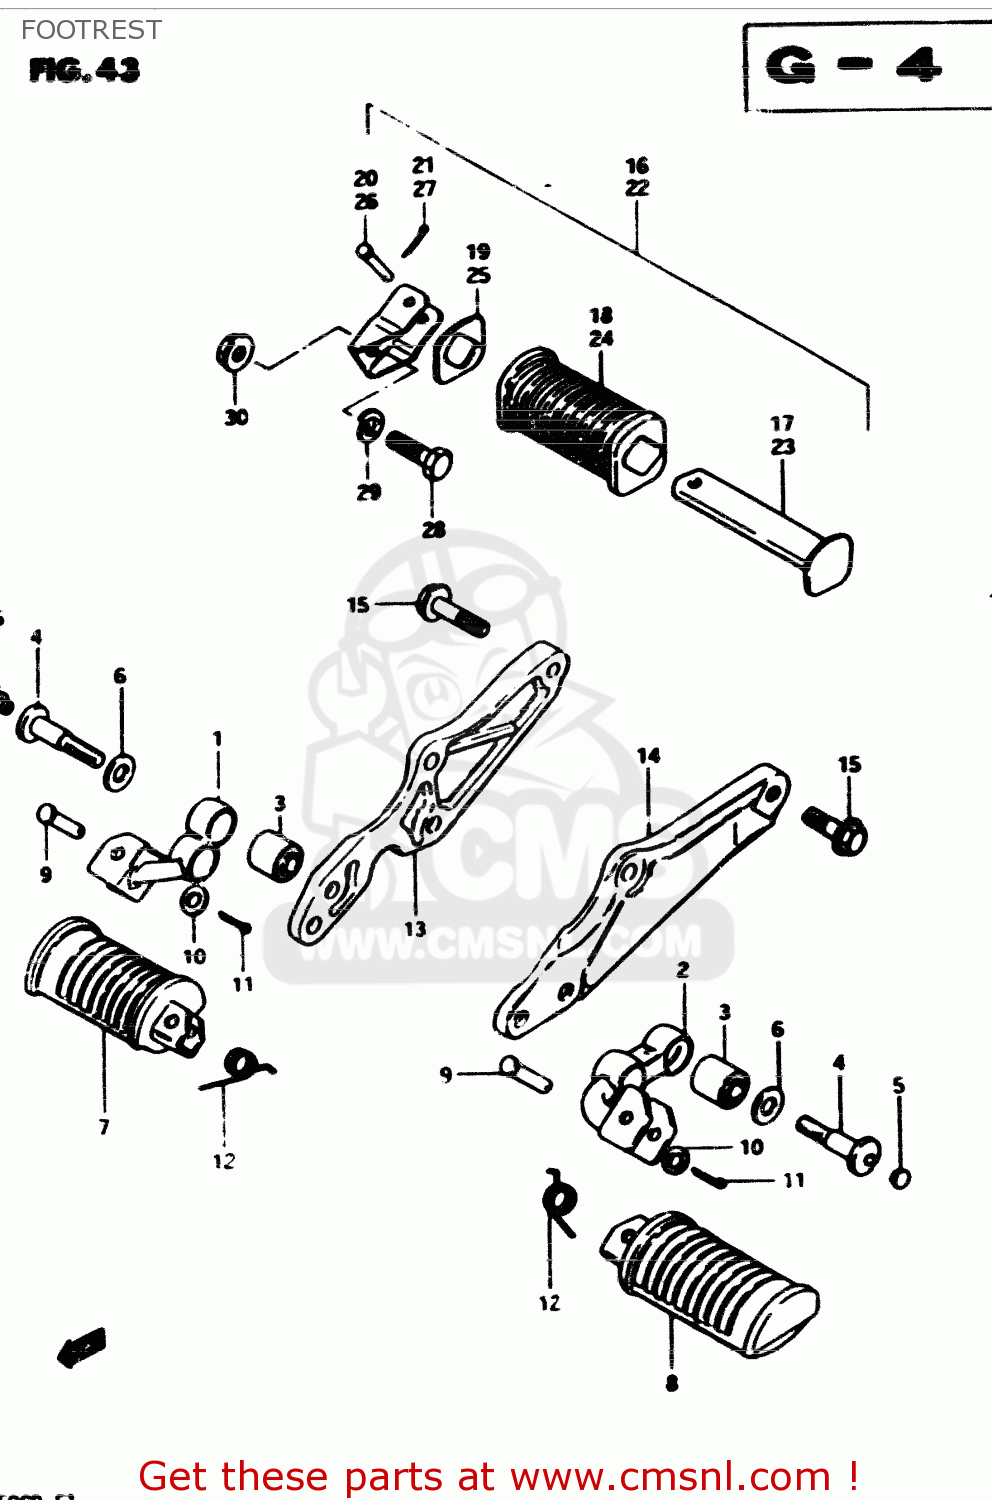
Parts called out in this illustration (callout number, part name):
1	BAR,FRONT FOOTREST,RIGHT
2	BAR,FRONT FOOTREST,LEFT
3	BUSH
4	BOLT(10X50)
5	CAP
6	WASHER(10.5X20X3.2)
7	RUBBER,PILLION FOOTREST,R
8	RUBBER,PILLION FOOTREST,L
9	PIN
10	WASHER
11	PIN 20X20
12	SPRING
13	BRACKET,MUFFLER,RIGHT
14	BRACKET,MUFFLER,LEFT
15	BOLT
16	FOOTREST ASSEMBLY,REAR,LEFT
17	BAR,REAR FOOTREST,LEFT
18	RUBBER,PILLION FOOTREST
19	WASHER,FOOTREST RUBBER
20	PIN
21	PIN
22	FOOTREST ASSEMBLY,REAR
23	BAR,REAR FOOTREST
24	RUBBER,REAR FOOTREST
25	WASHER,REAR FOOTREST RUBBER
26	PIN
27	PIN 20X20
28	BOLT,M10X1.25X
29	LOCK WASHER
30	NUT
